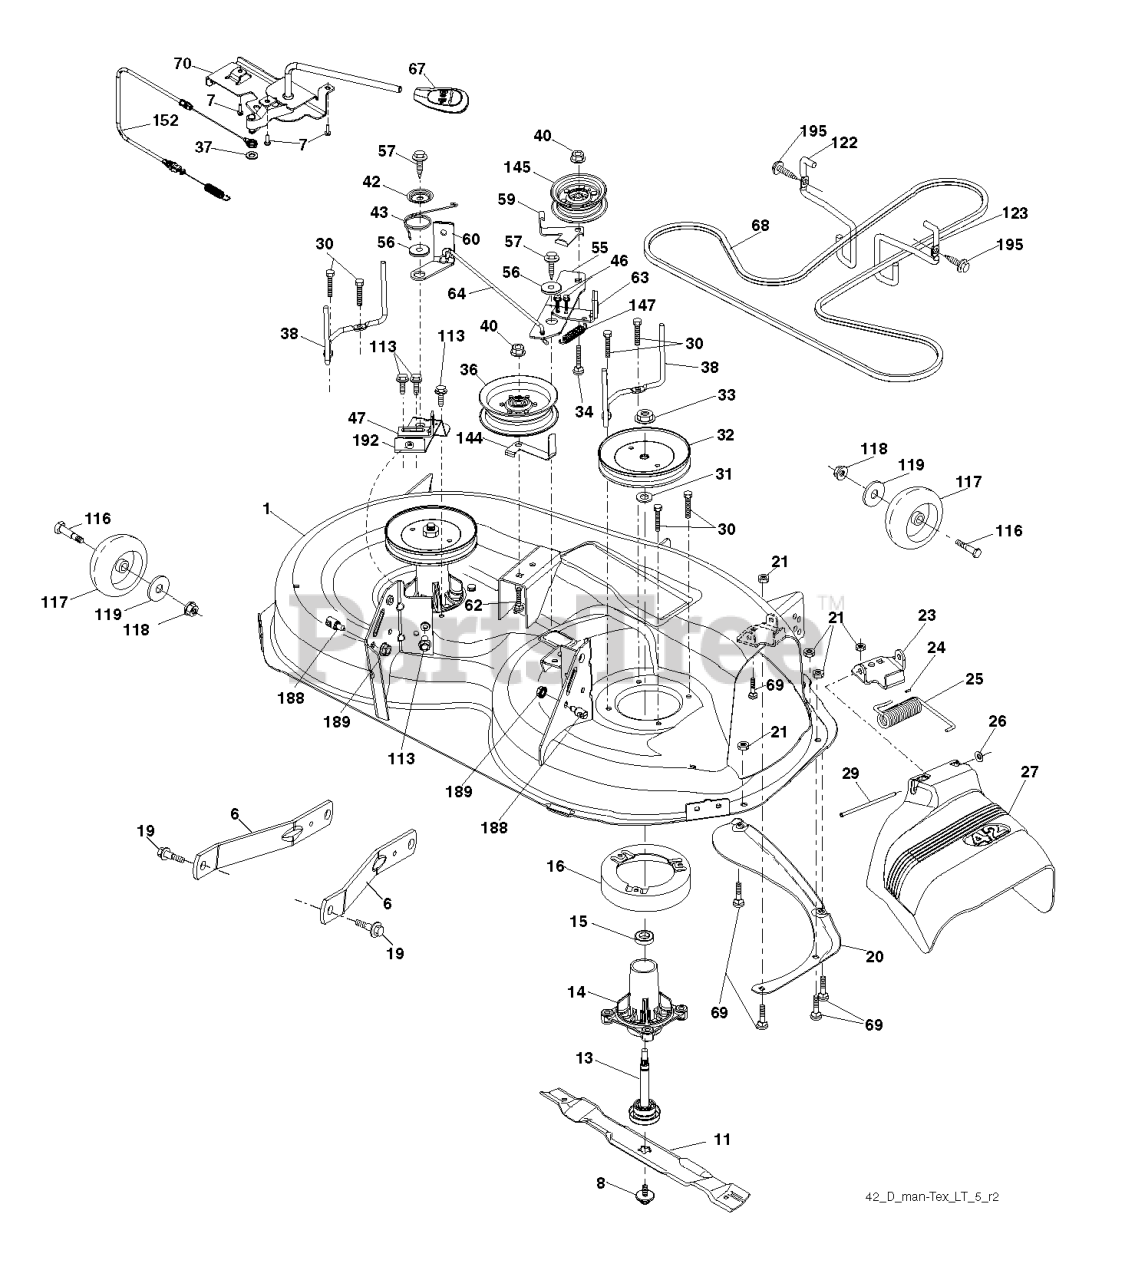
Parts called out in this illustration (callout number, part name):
1	DECK.WELDMENT.42"
6	ARM.SUSPENSION.MOWER.R
7	SCREW.#10 X 0.750.BOS
8	BOLT.WASHER.ASM.7/16-2
11	42" HI-LIFT BLADE
13	SHAFT.ASM.MDRL.N/GREASE.38
14	RP.HOUSING.MANDREL.4PT.
16	STRIPPER.MANDREL.ROUND.BLACK
19	BOLT.SHOULDER
20	BAFFLE.VORTEX
21	LOCKNUT
23	BRKT.DEFLECTOR.38"2005+
24	CAP-SLEEVE LT
25	SPRING.TORSION.DEFLECT
26	NUT PUSH M
27	SHIELD.DEFLECTOR.MOWER.42"BLAC
29	ROD.HINGE
30	SCREW, WASHER HEAD
31	WASHER.SPACER.MANDREL
32	PULLEY.MANDREL.5.438.PD
33	NUT.FLANGE.LOCK.TOP
34	BOLT.3/8-16X1.50
36	PULLEY.IDLER.2006
37	WASHER
38	KEEPER.BELT.LH.MANDREL
40	NUT LOCK FLG 3/8-16 UNC
42	SPRING.TORSION.BRAKE
43	SRPING.TORSION.RETAINE
46	SCREW.1/4-20X5/8
47	BRKT.CLUTCH.CABLE
56	SPACER.RETAINER
57	SCREW 3/8-16X1
59	GUARD, BELT
60	ARM BRAKE MOWER
63	ARM BRAKE MOWER
64	LINK BRAKE
67	HANDLE.CLUTCH.CABLE.LT
68	BELT.DRIVE.MOWER.TEX.42"
69	BOLT
70	CLUTCH.ASM.MANUAL.LT.PRED
113	BOLT.5/16HEX.WHS.HD
116	BOLT M
117	WHEEL.GAGE.HALF.SPOKED
118	LOCKNUT
119	WASHER.5/16.FLAT.STE.STD.
122	KEEPER BELT ENGINE LH
123	KEEPER BELT RH
144	KEEPER.BELT.MOWER
145	PULLEY.IDLER.48"PRIMARY
147	RETURN SPRING
152	CLUTCH CABLE
188	STUD.FASTNER.W/ANTI-ROTATE
189	NUT LOCK HEX FLANGE 5/16-18
192	BRKT.BRAKE.STAND.LH.
195	SCREW, 3/8-16X3/4
208	SCREW 3/8-16X1/2
